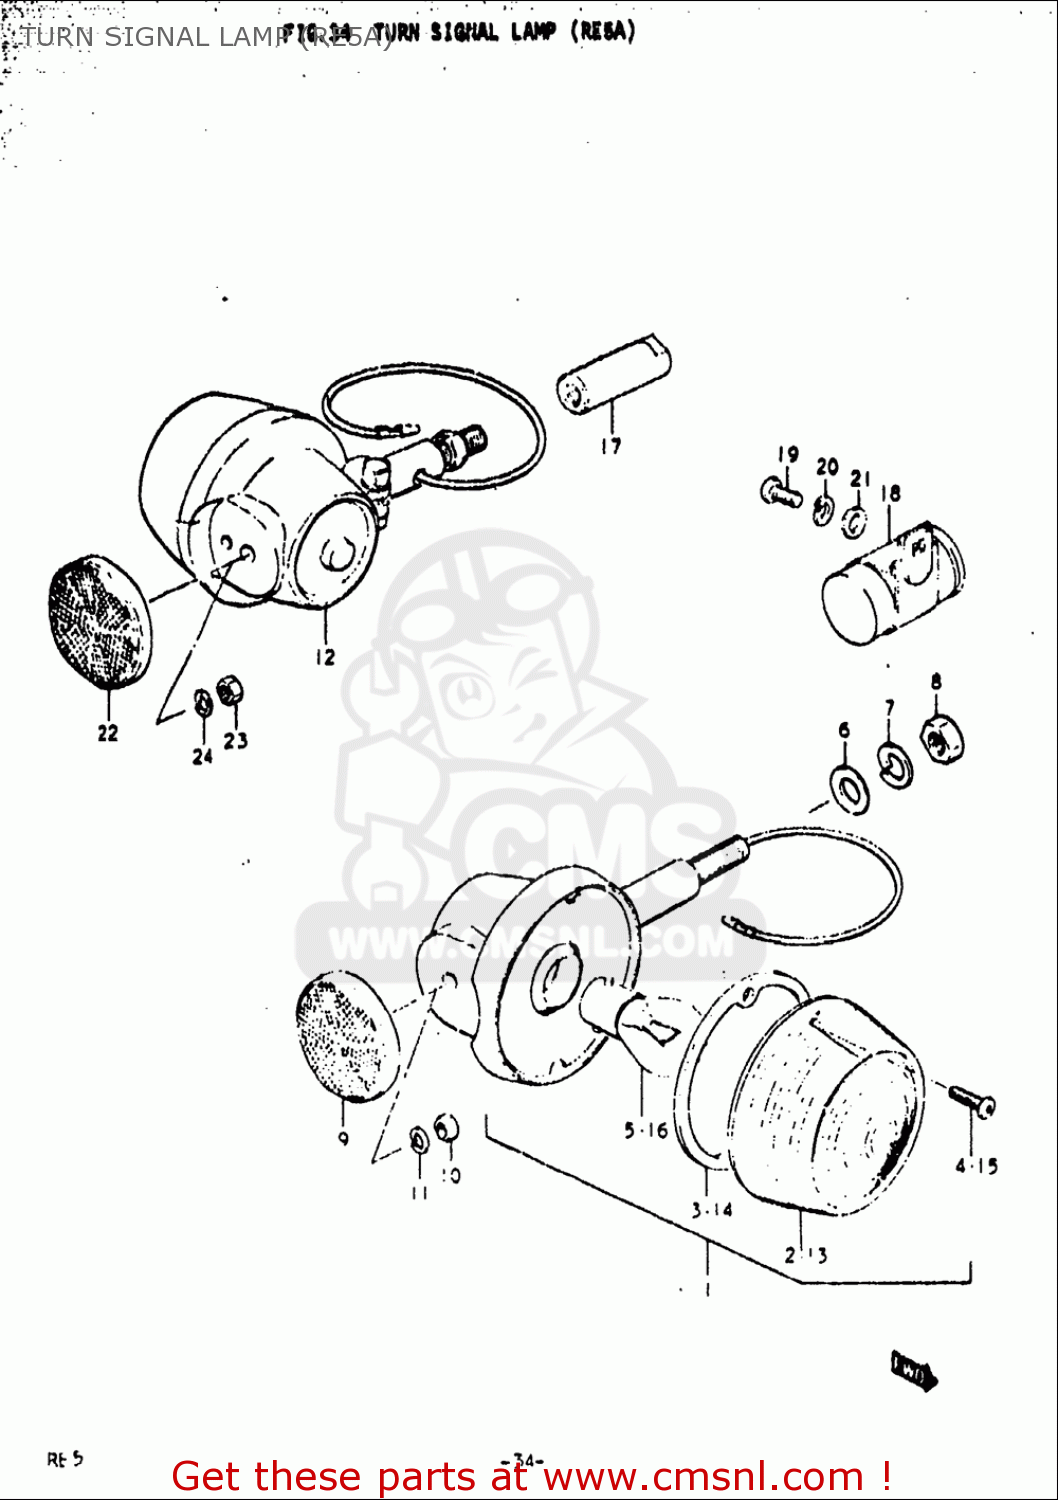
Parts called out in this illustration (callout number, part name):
2	LENS
3	GASKET,TURNSIGNAL LENS (NAS)
4	SCREW
5	BULB(12V23W,STANLEY,A4577A)
6	WASHER
7	WASHER,LOCK
8	NUT
9	REFLEX REFLECTOR,RR
10	NUT
11	WASHER,LOCK
13	LENS
14	GASKET,TURNSIGNAL LENS (NAS)
15	SCREW
16	BULB(12V23W,STANLEY,A4577A)
18	RELAY ASSY,TURNSIGNAL
19	SCREW
20	WASHER,LOCK
21	WASHER
23	NUT
24	WASHER,LOCK
